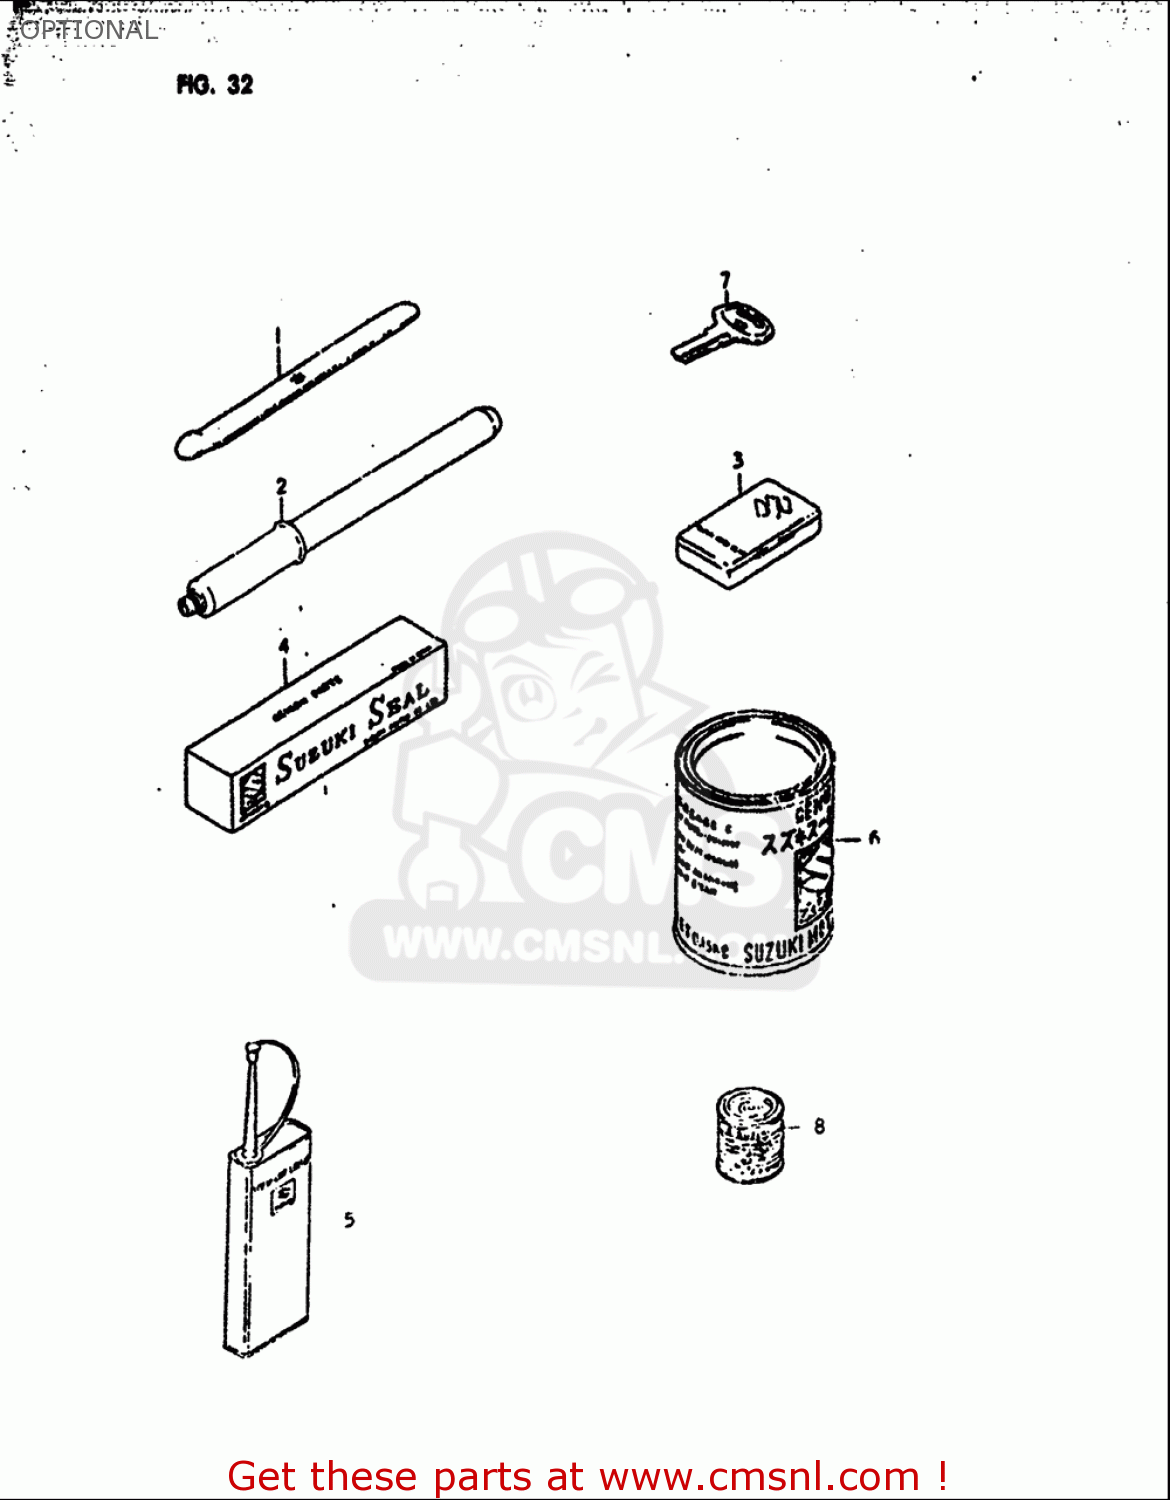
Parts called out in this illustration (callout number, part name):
1	LEVER,TIRE
4	BOND 1104
5	THREAD LOCK NO.1401 CLEAR 200G
6	GREASE(C)EP2 LITHIUM 150G
7	KEY,BLANK
